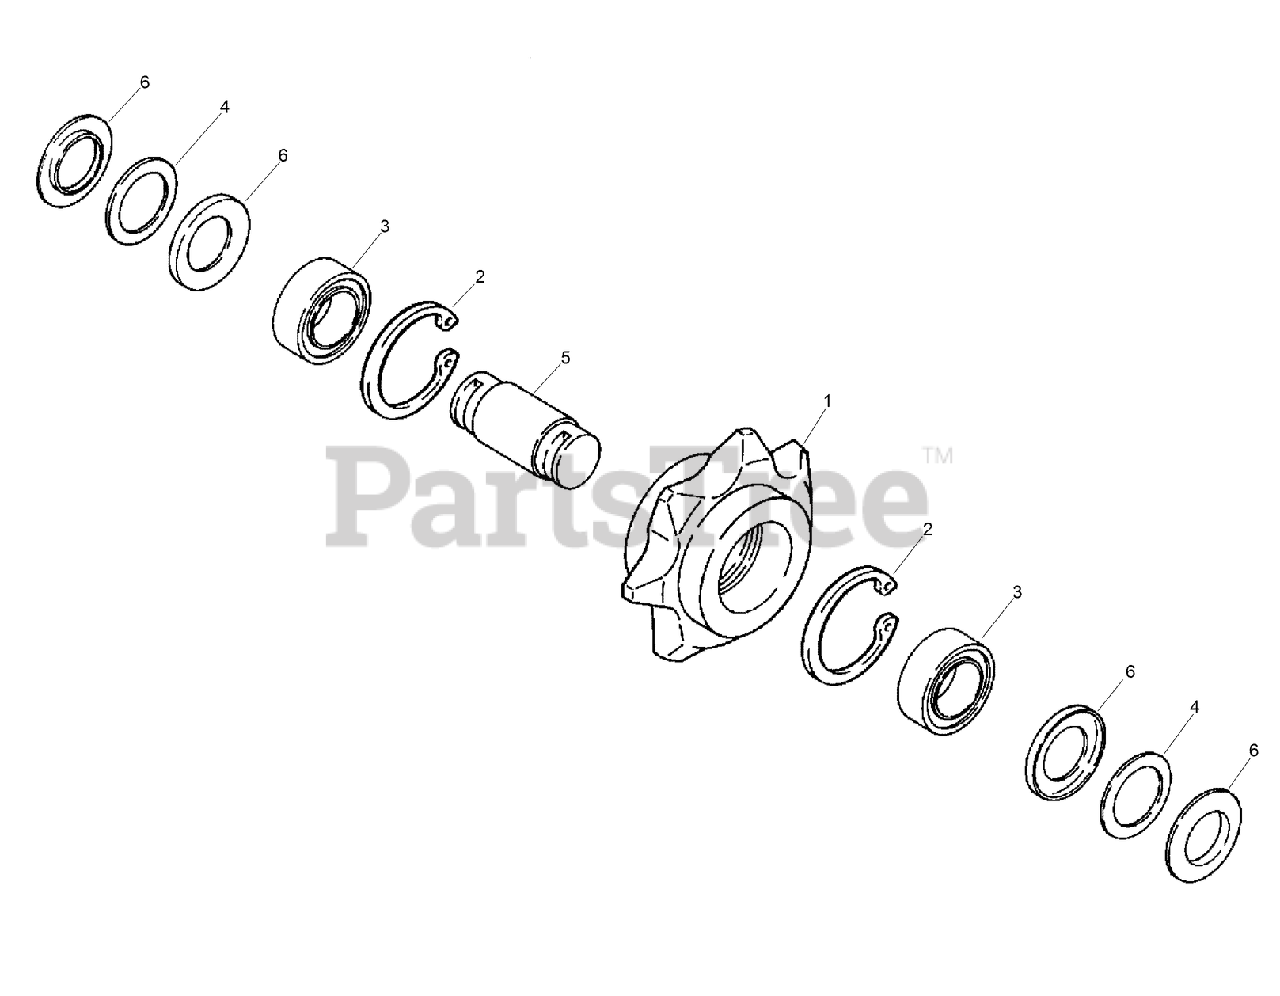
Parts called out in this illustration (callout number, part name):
1	SPROCKET - Idler, 311 Chain
1	SPROCKET - Idler, 408 Chain
2	RING - Retaining, # 393
3	BEARING - Ball, Idler Sprocket
4	WASHER - Special
